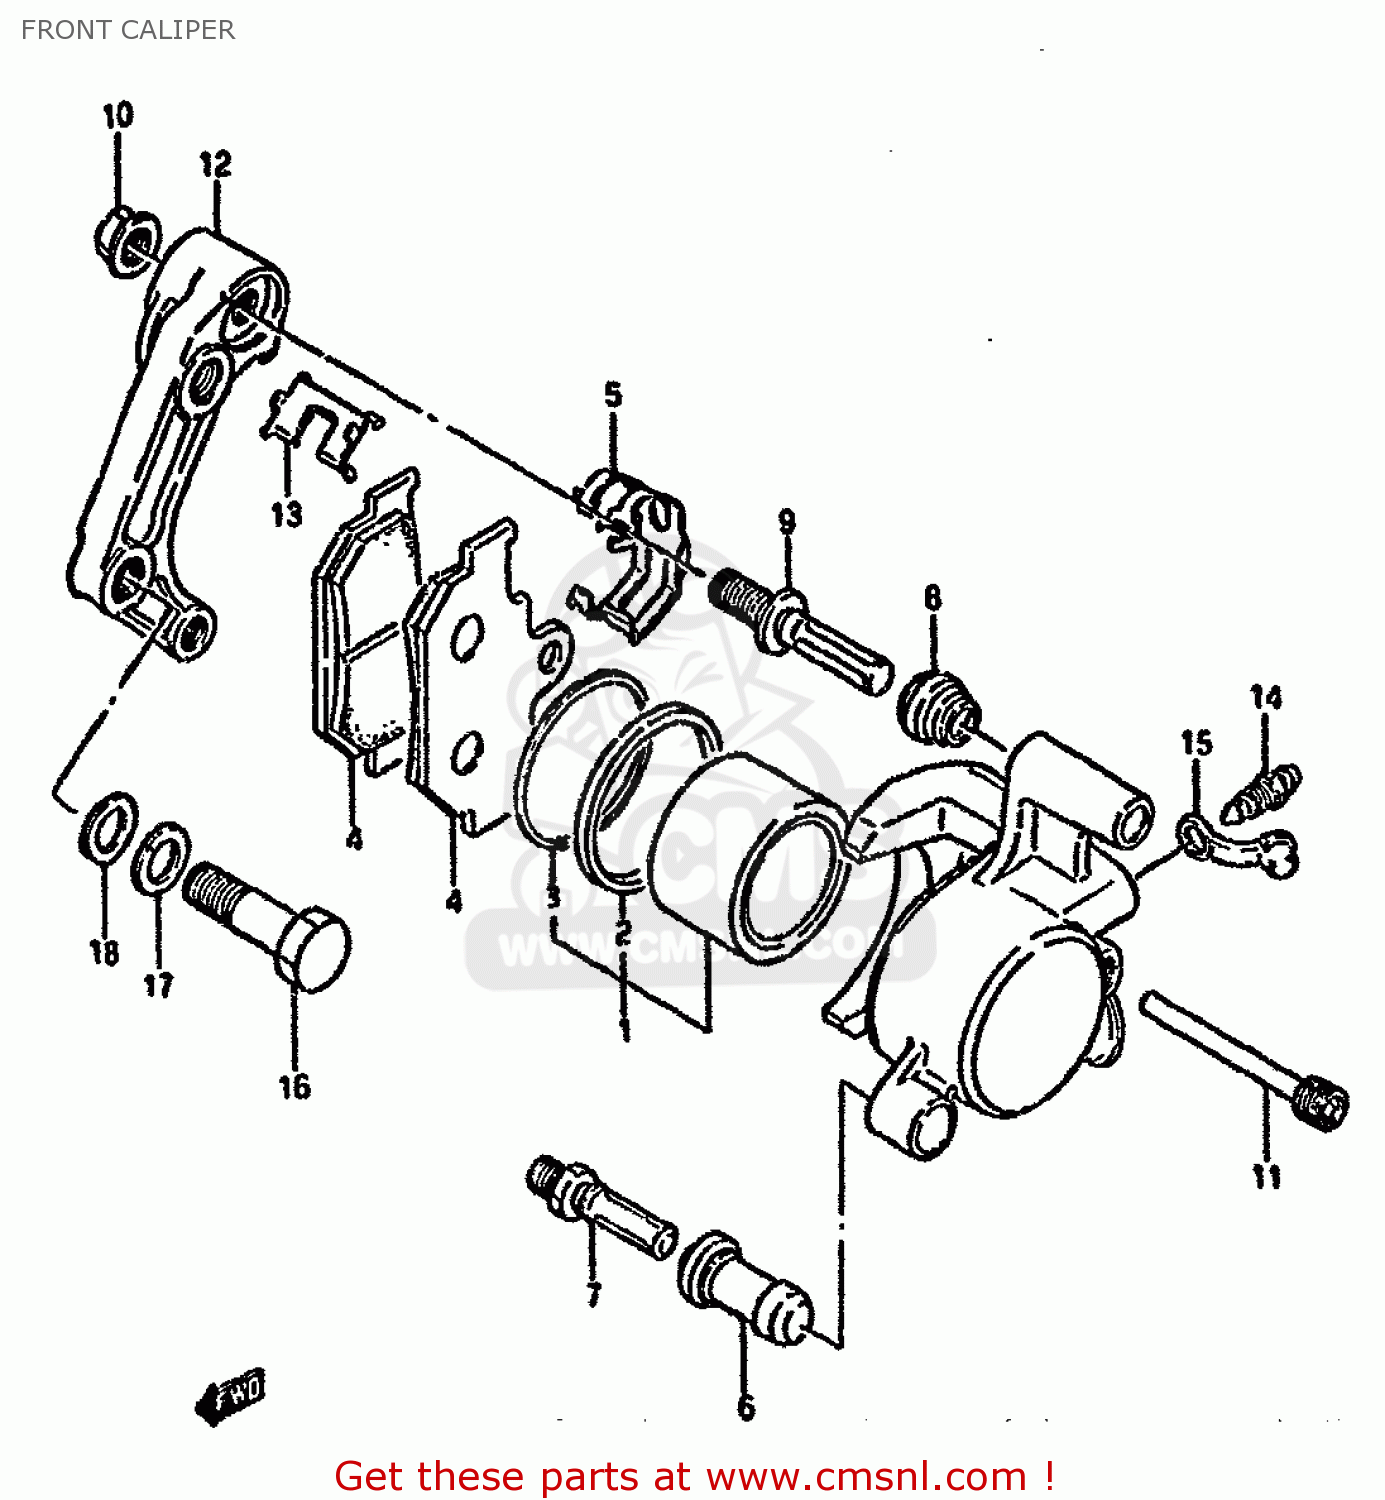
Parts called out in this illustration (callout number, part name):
1	PISTON SET
2	SEAL,PISTON
3	SEAL,DUST
4	PAD
5	SPRING
6	BOOT
7	PIN,BOLT
8	BOOT
9	PIN,SLIDE
10	NUT,SLIDE PIN
11	PIN,HANGER
12	BRACKET
13	RETAINER
14	BLEEDER
15	CAP,BLEEDER
16	BOLT(10X38)
17	WASHER,LOCK
18	WASHER
